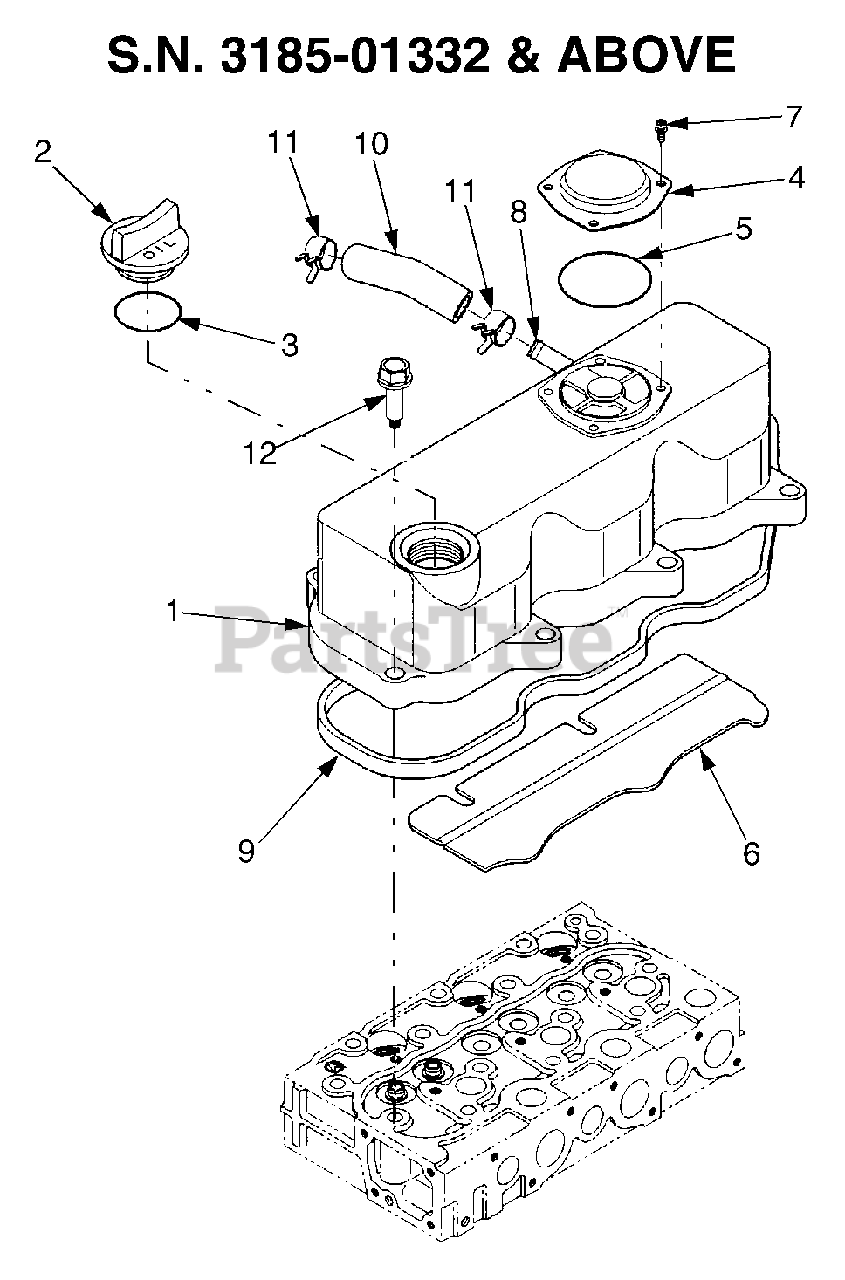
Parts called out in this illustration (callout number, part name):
1	Cover, Cylinder Head
2	Plug, Oil Filler
6	Oil Protector
8	Connector, Airbreather
9	Gasket, Head Cover
10	Pipe, Breather
